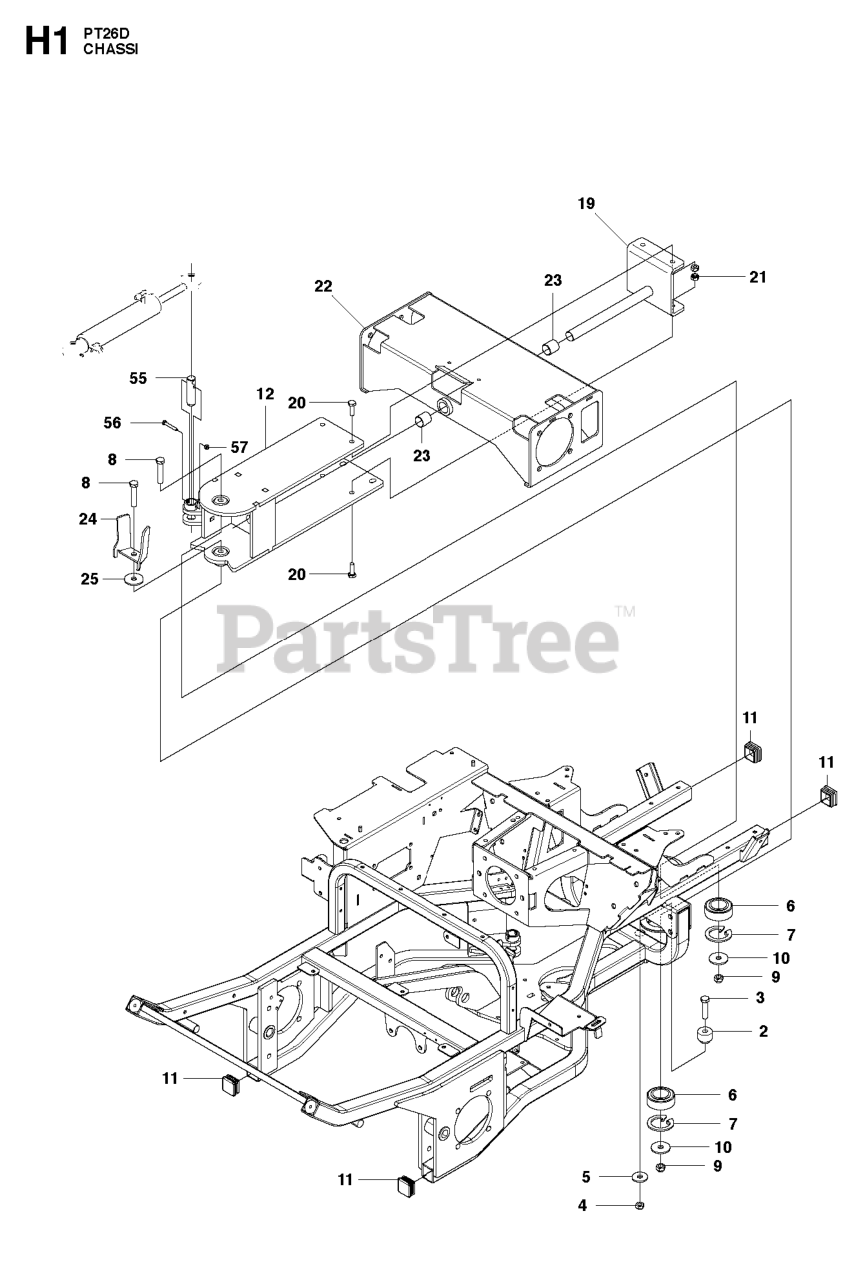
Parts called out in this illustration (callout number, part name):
2	STOP SLEEVE STEERING STOP
19	SWING AXLE
21	NUT
23	BUSHING
24	GUIDE PLATE HYDRAULIC HOSES
57	LOCKNUT M6
